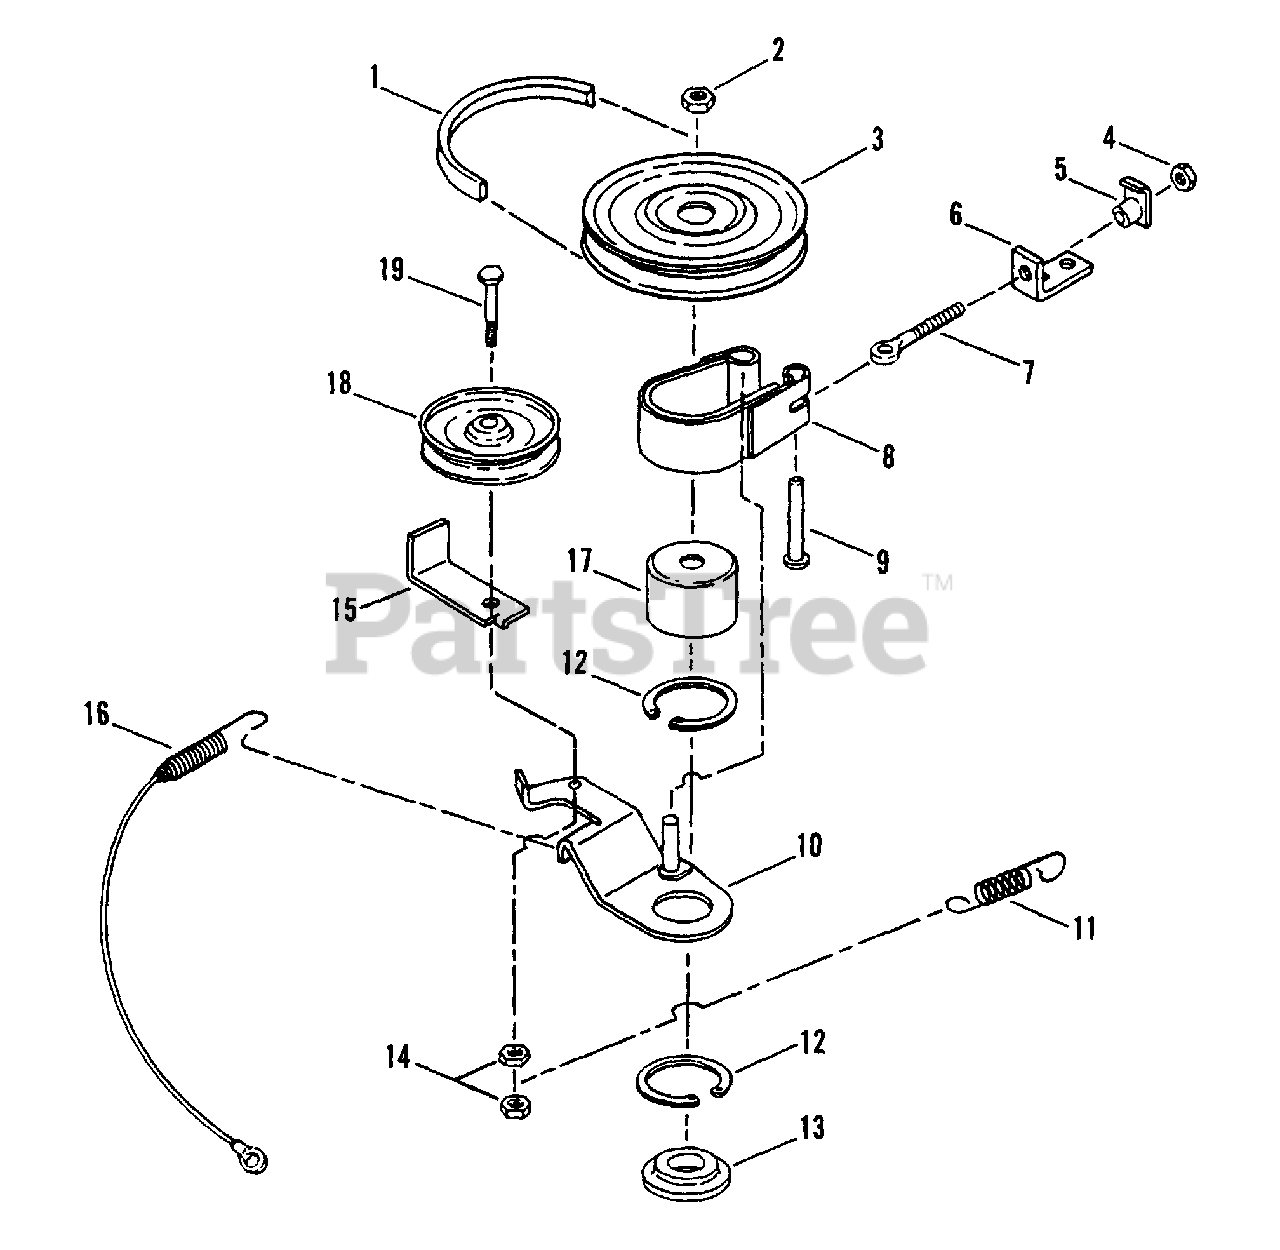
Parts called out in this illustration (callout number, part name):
1	BELT, Drive
2	NUT, 3/4-16 Hex Jam
3	PULLEY, Drive
4	NUT, 1/4-20 Hex
5	TEE-NUT, 1/4-20
6	ANCHOR, Brake
7	BOLT, 1/4-20 Eye
8	ASSEMBLY, Brake Band
9	PIN, Clevis, 1/4 x 1-1/4"
10	ASSEMBLY, Brake Arm
11	SPRING, Blade Brake
12	RING, 2" External Retaining
13	WASHER, Spindle
14	NUT, 3/8-24 Hex Center Lock, Grade 5
15	GUIDE, Belt
16	CABLE, Blade
17	DRUM, Brake
18	PULLEY, Idler
19	SCREW, 3/8-24 x 2" Hex Head Cap
